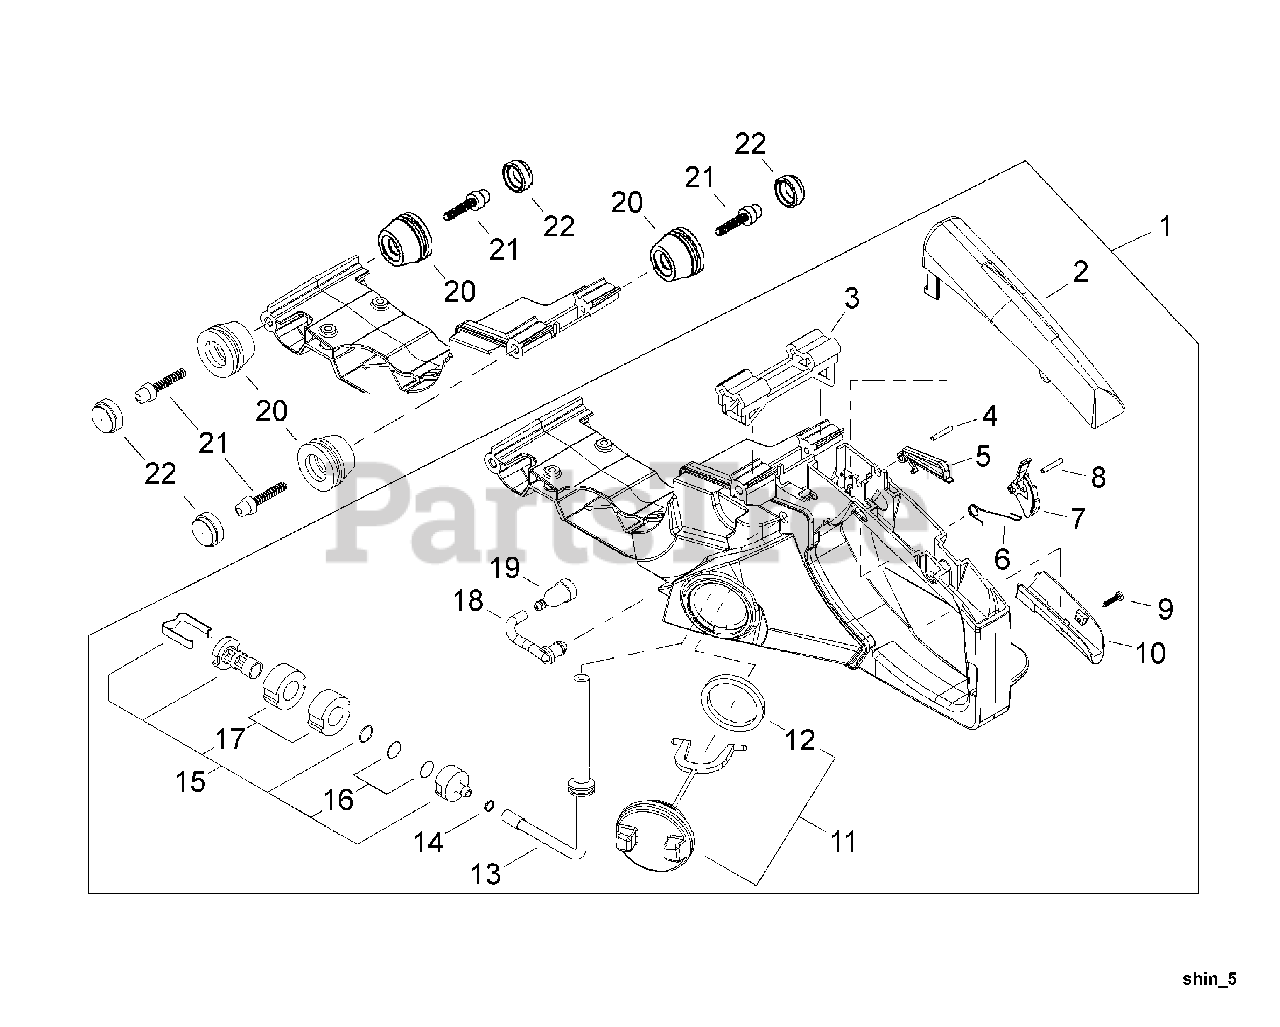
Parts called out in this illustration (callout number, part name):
1	HANDLE ASSY, REAR
2	GRIP, UPPER
3	CUSHION, STOPPER
4	PIN, SPRING Ø4×22 MM
5	LEVER, THROTTLE LOCKOUT
6	SPRING, THROTTLE RETURN
7	TRIGGER, THROTTLE
8	PIN 4×25
9	SCREW, TAPPING M4×22
10	GRIP, LOWER
11	CAP ASSY, FUEL
12	GASKET, FUEL CAP
13	PIPE, FUEL
14	CLIP Ø6
15	FILTER, FUEL
16	SCREEN, FILTER
17	FILTER, FUEL
18	PIPE, FUEL VENT
19	VENT ASSY
20	CUSHION 5
21	BOLT 5
22	CAP, CUSHION
